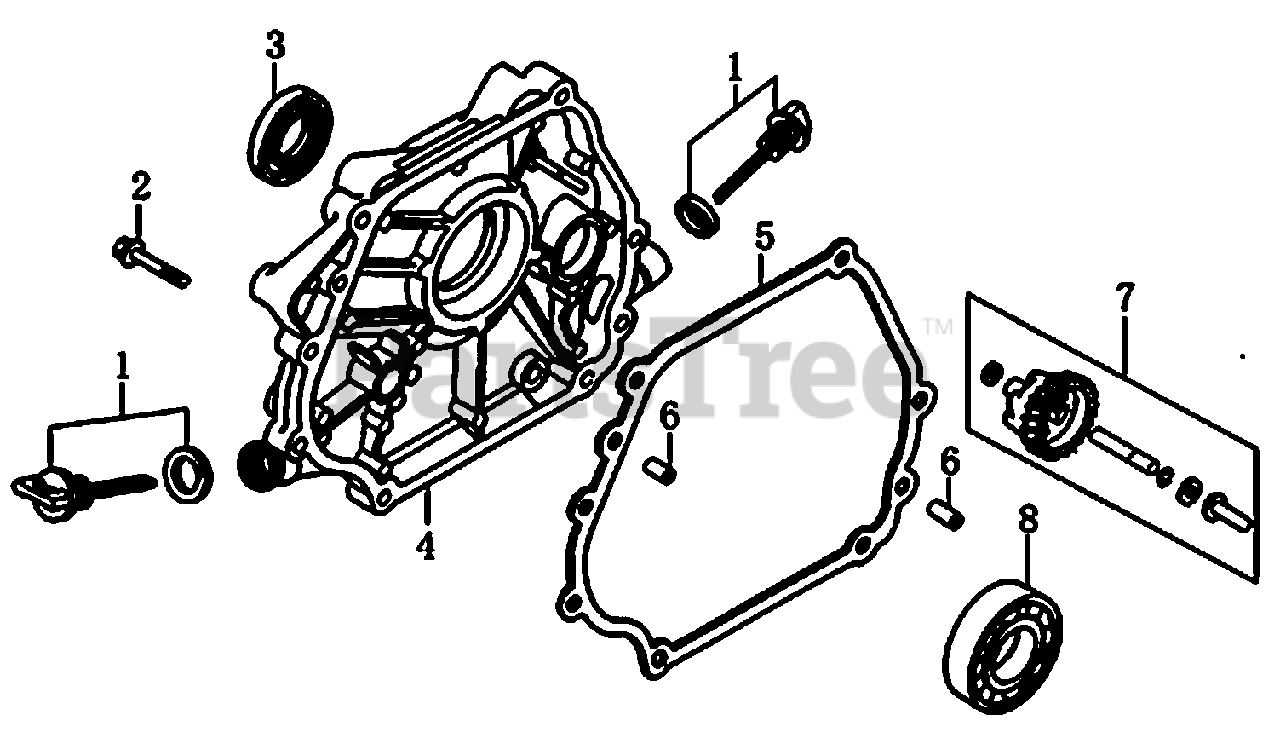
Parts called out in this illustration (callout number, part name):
1	DIPSTICK & WSHR ASSY.
2	BOLT, FLANGE 8X35
3	SEAL, OIL 30x46x8
4	COVER, CRANKASE
5	GASKET, CRANKCASE COVER
6	PIN, DOWEL 8x12
7	GOVERNOR ASSY.
8	BEARING, BALL 6206
